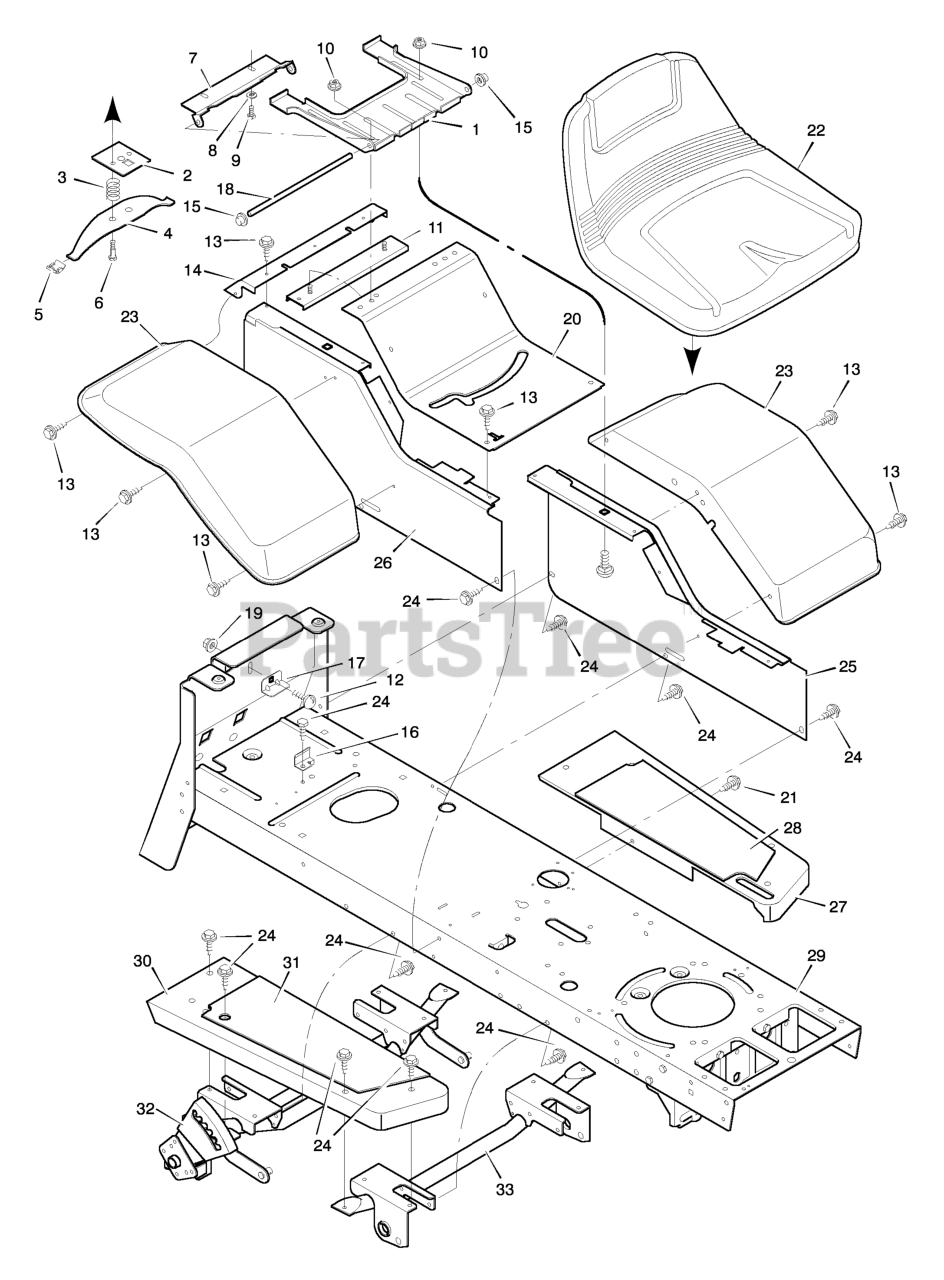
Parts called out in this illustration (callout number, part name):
1	Bracket, Seat
2	Plate Assembly, Switch
3	Spring, Compression
4	Spring, Seat
5	Glide, Spring
6	Bolt, Shoulder
7	Support, Seat
8	Lockwasher
9	Bolt, Hex
10	Locknut, Flange
11	Channel Assembly
12	Bolt, Carriage
14	Insert, Rear
15	Push On Cap
16	Clip, Battery
17	Clamp, Battery
18	Rod, Pivot
19	Locknut
20	Panel, Top
21	Fastener, Panel
25	Panel, Left
26	Panel, Right
27	Running Board, Left
28	Mat, Left
29	Frame Channel
30	Running Board, Right
31	Mat, Right
32	Lifter and Support Assembly
33	Support Assembly, Front
